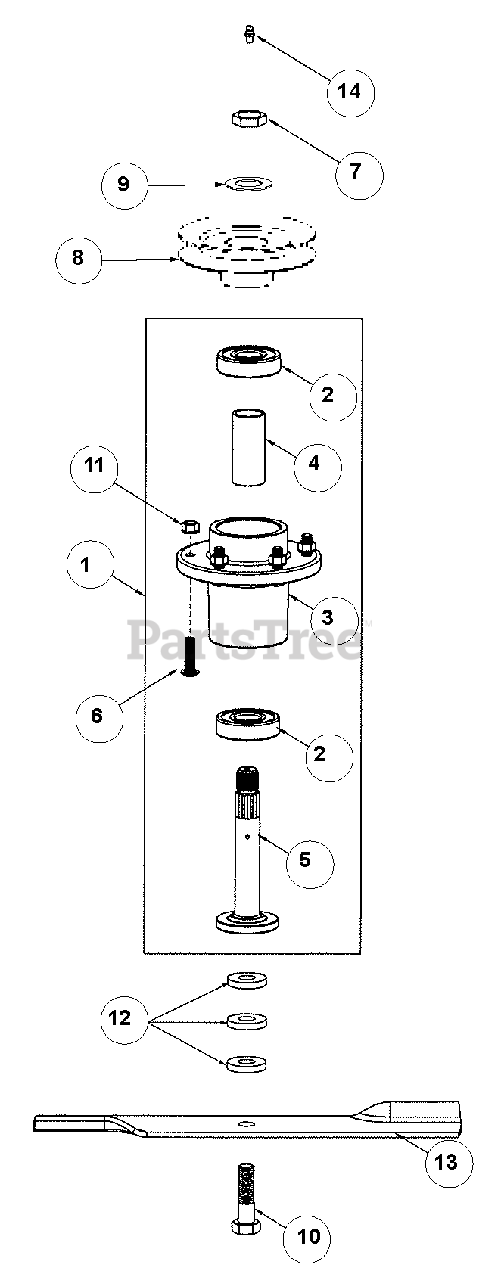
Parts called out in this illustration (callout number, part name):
1	Spindle Assembly - Includes 2, 3, 4, 5, 6
3	Casting, Spindle w/Studs
4	Spacer, 1.250 x 1.000 x 2.780 x 2.772
5	Shaft, Spindle
6	Bolt, .38-16 x 1.25 Rib
7	Nut, .75-16 Flange Grade 8
8	Pulley, Cutter Housing - See Mower Assembly
9	Washer, .75 x 1.3125 x .120
10	Bolt, Blade - .625-11 x 2.25 Grade 8
11	Nut, .38-16 Std Hex Grade 5
12	Spacer, Blade Bolt
13	18.0" Blade, 36" Deck (400)
14	Zerk, Grease
